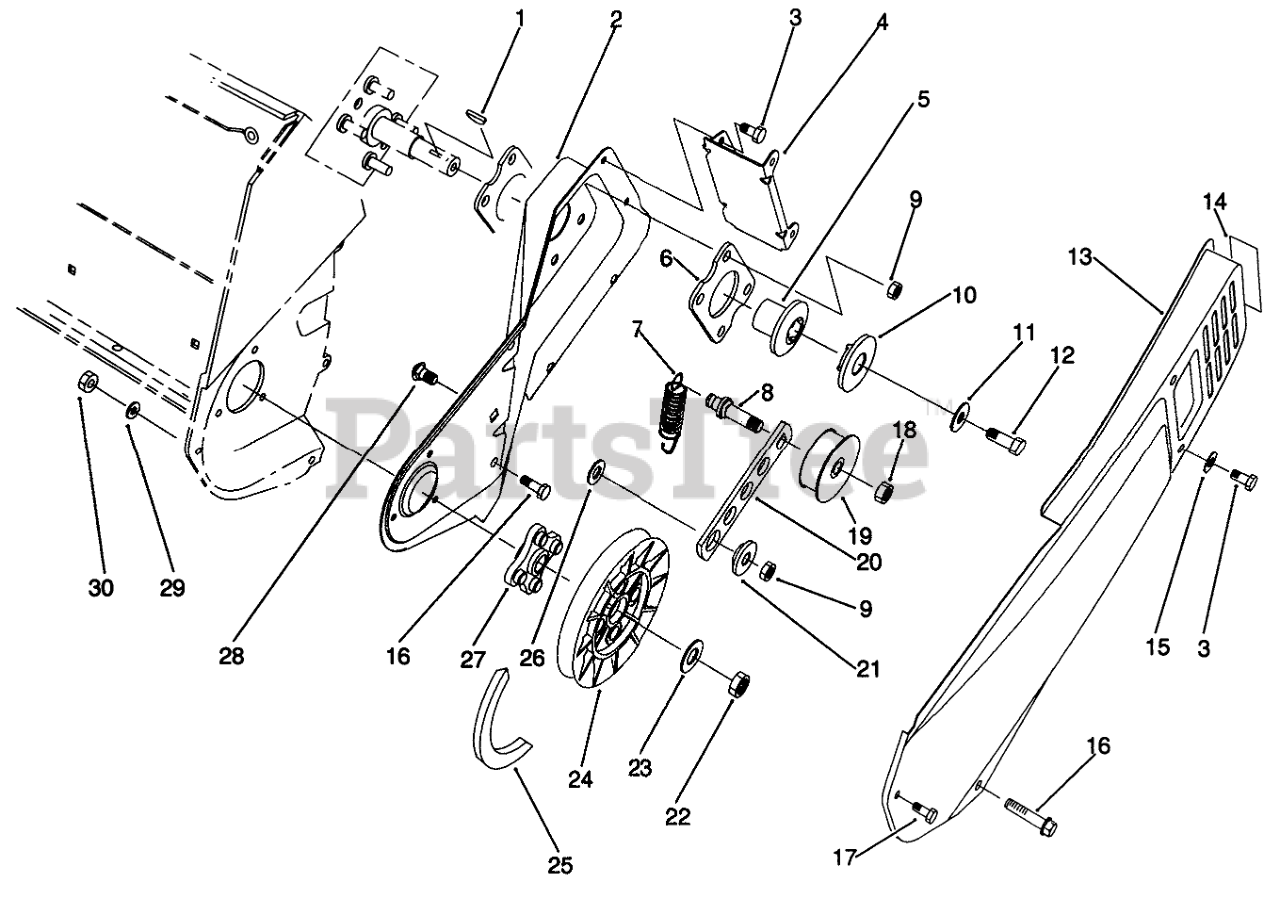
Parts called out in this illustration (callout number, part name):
1	KEY-WOODRUFF
2	Sideplate-LH
3	SCREW-HWH
4	Bracket-Cover
5	Hub-HALF SHEAVE
6	Plate Engine
7	SPRING-EXTENSION
8	PIN-IDLER
9	NUT-LOCK, NI
10	CAP-HALF SHEAVE
11	WASHER-FLAT
12	SCREW-HH
13	Cover-Belt
14	Decal
15	WASHER-FLAT
16	SCREW-PLASTIC
18	NUT-LOCK, NI
19	PULLEY-IDLER
20	ARM-IDLER
21	BUSHING-IDLER
22	NUT-LOCK, NI
23	WASHER-FLAT
24	PULLEY-DRIVEN
25	V-BELT
26	WASHER
28	SCREW-CARR
29	WASHER-FLAT
30	NUT-LOCK, NI
